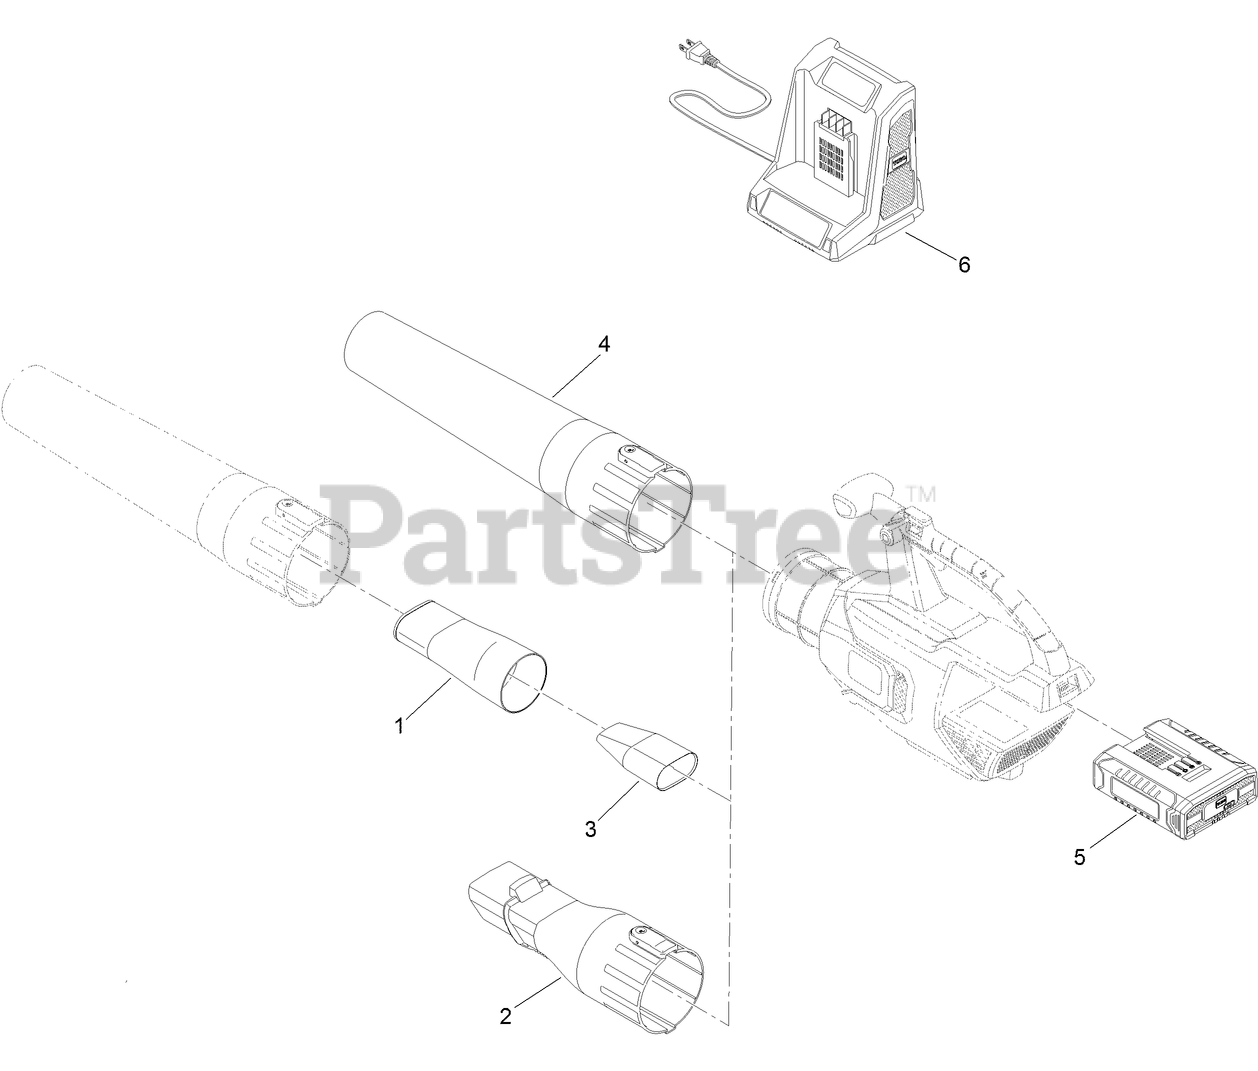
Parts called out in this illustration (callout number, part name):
1	Adapter-Oscillator, MPH
2	ADAPTER-CLEANER, GUTTER
3	Adapter-Insert, MPH
4	TUBE-BLOWER
5	BATTERY-40V MAX
6	CHARGER-40V MAX
